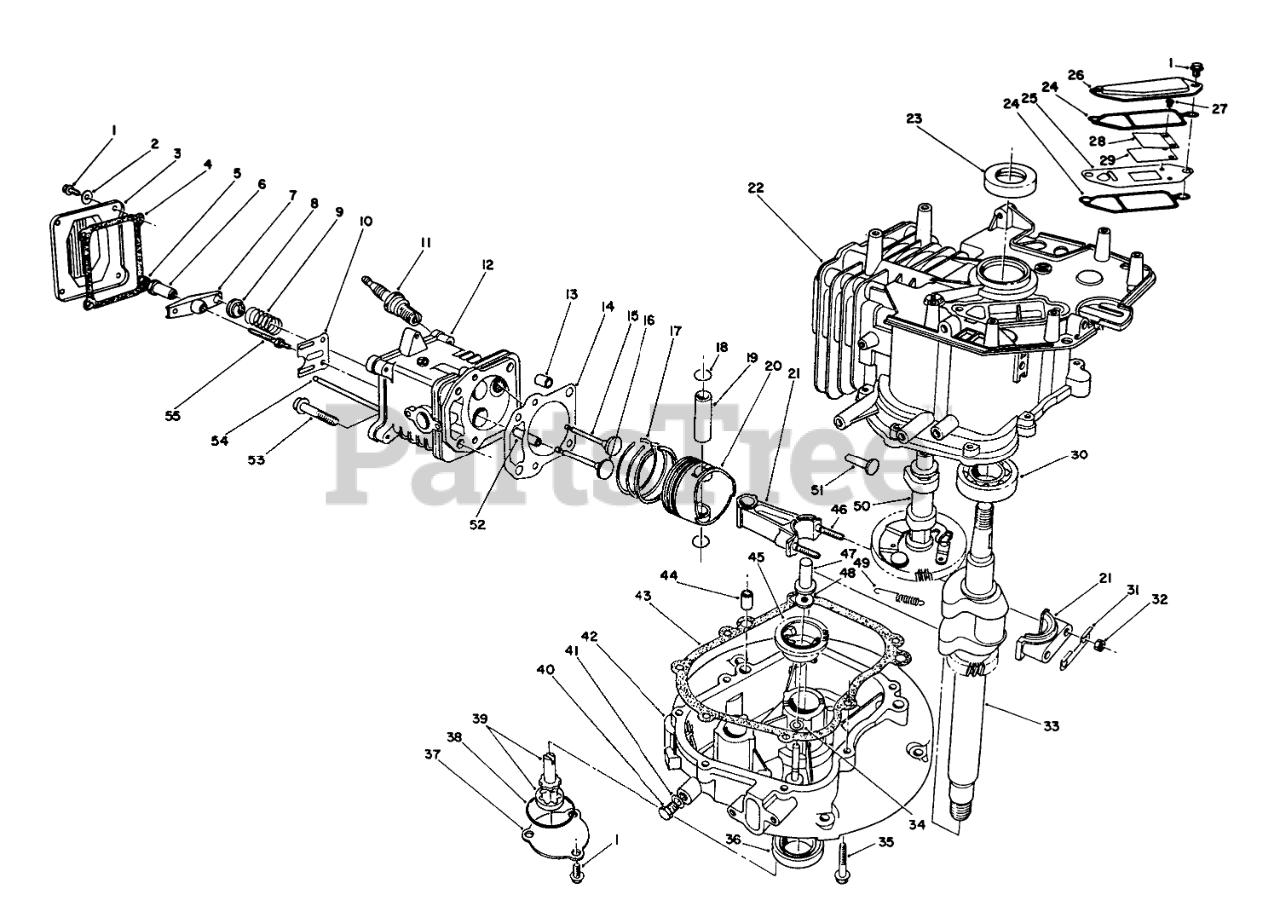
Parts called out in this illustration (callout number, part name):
2	WASHER
3	COVER
4	GASKET
6	PIVOT
8	RETAINER
9	SPRING
10	GUIDE
11	SPARK PLUG
12	Head-Cylinder (Incl. Ref. #52)
14	GASKET
15	VALVE-EXHAUST
16	VALVE-INTAKE
17	RING SET
18	CIRCLIP
20	PISTON
21	Connecting Rod Assembly (Incl. Ref. #31, 32 & 46)
22	Block-Engine (Incl. Ref. #23 & 30)
24	GASKET
25	Plate-Breather
26	COVER
27	Screw-Reed Valve
28	Retainer-Reed Valve
29	Valve-Reed
30	BEARING
31	Plate-Lock
33	CRANKSHAFT
34	WASHER
37	COVER
38	O-RING
39	OIL PUMP
40	OIL DRAIN PLUG
41	GASKET
42	Crankcase
43	GASKET
45	GOVERNOR FLYWEIGHT ASM
47	PLUNGER
48	WASHER
49	SPRING
50	Camshaft Assembly (Incl. Ref. #49)
51	TAPPET
52	GUIDE
